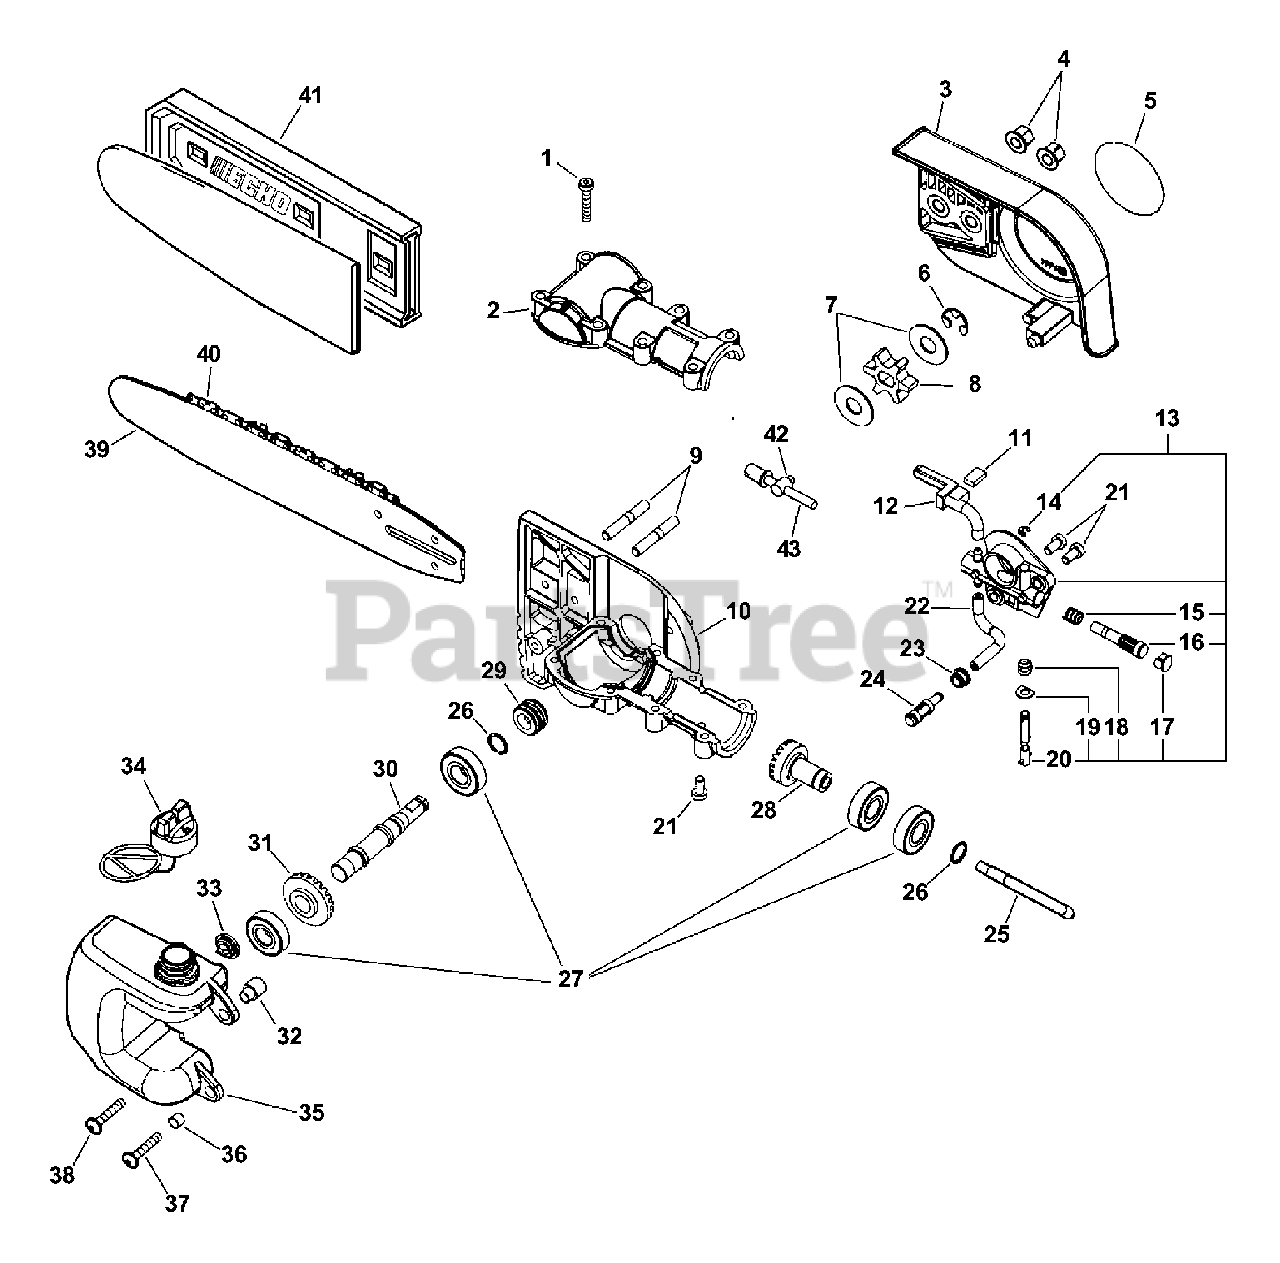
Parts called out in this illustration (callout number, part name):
1	SCREW - 5X25
2	CASE, GEAR - UPPER
3	GUARD, SPROCKET
4	NUT - 6 -- FLANGE
5	LABEL - ECHO
6	RING, RETAINING
8	SPROCKET, DRIVE
9	STUD - 6
10	CASE, GEAR - LOWER
11	PAD, FOAM
12	PIPE, OIL OUTLET
13	AUTO-OILER ASSY
14	RING, RETAINING
15	SPRING, PLUNGER
16	PLUNGER ASSY
17	CAP, OIL PUMP
20	NEEDLE, ADJUST
21	SCREW - 5X10
22	PIPE - 3X6X75 -- BLACK
23	GROMMET
24	FILTER, OIL
25	CONNECTOR, SHAFT
26	RING, RETAINING - 12
27	BEARING, BALL - 6001
28	GEAR - BEVEL
29	GEAR - WORM
30	GEAR - SHAFT
31	GEAR - BEVEL
34	CAP ASSY
35	TANK, OIL
37	SCREW - 5X16
38	SCREW - 5X20
39	GUIDE BAR - 10" (25cm) Intenz
40	SAW CHAIN - 10" (25cm)
41	COVER, GUIDE BAR - 10" (25cm)
42	TENSIONER, CHAIN
43	SCREW, TENSIONER
